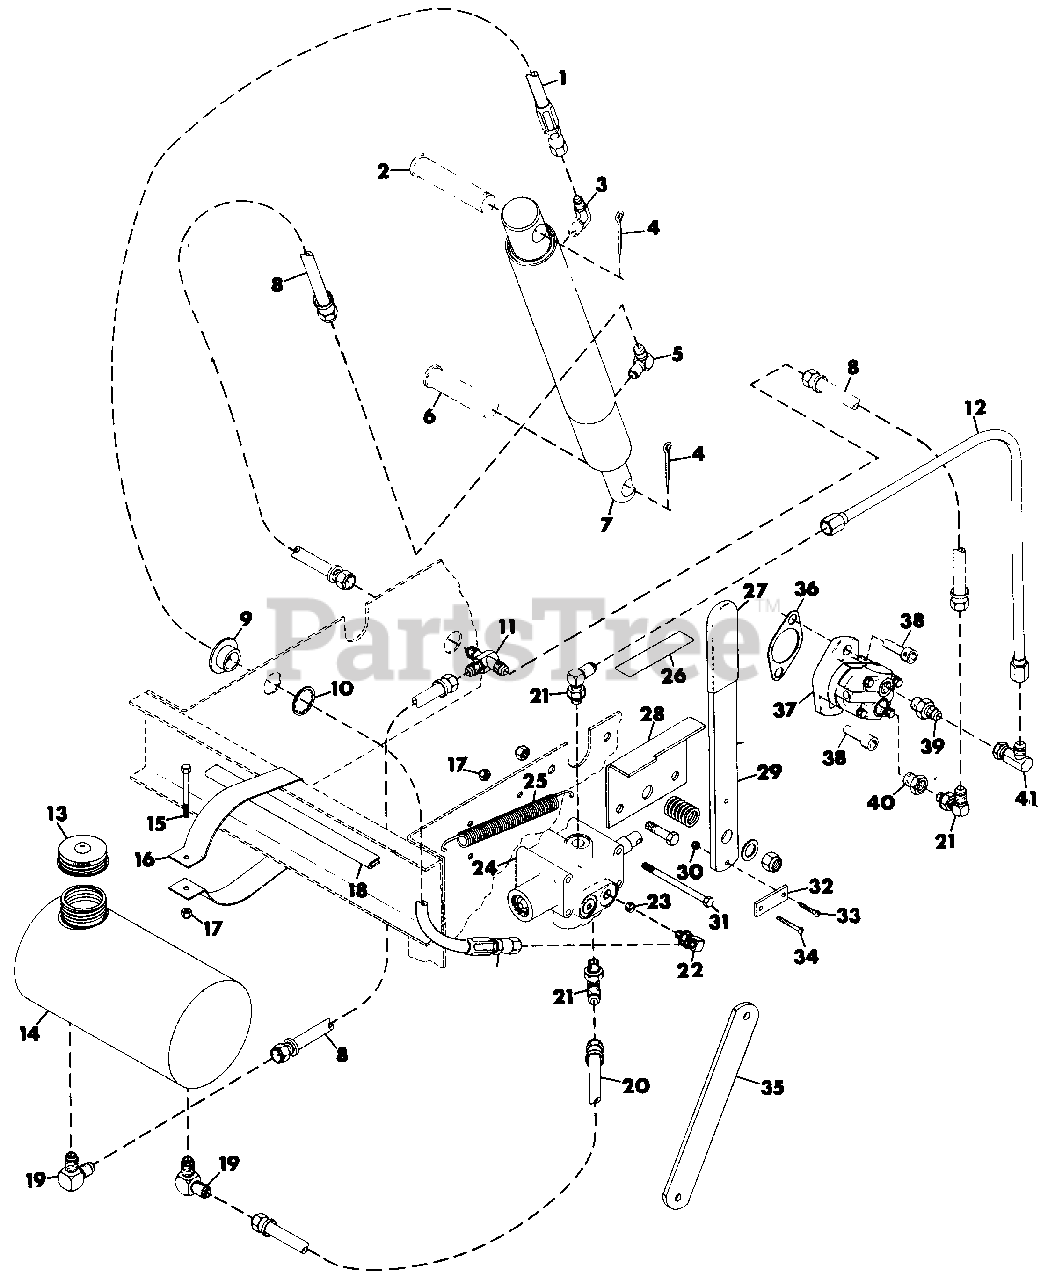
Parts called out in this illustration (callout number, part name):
1	HOSE, HYDRAULIC
2	PIN, CLEVIS
3	ADAPTOR
4	PIN, COTTER .125X1.25
5	ADAPTOR, HYDRAULIC
6	PIN, CLEVIS
7	CYLINDER, HYDRAULIC
8	HOSE, HYDRAULIC
9	BUSHING, NYLON .76X1X.6 FLG.
10	RING, RETAINING INTERNAL TOOTH
11	ADAPTOR, TEE
12	LINE, HYDRAULIC PUMP TO VALVE
13	CAP, HYDRAULIC TANK
14	TANK, HYDRAULIC
15	BOLT, HEX 1/4-20X1.75
16	STRAP, HYDRAULIC TANK
17	NUT, LOCK 1/4-20
18	MOULDING, TANK
19	ADAPTOR
20	ASSEMBLY, HOSE VALVE TO TANK
21	ADAPTOR
22	ADAPTOR
23	PLATE, FLOW RESTRICTION
24	VALVE, CONTROL
25	SPRING, EXTENSION 5.5X.5X20 RATE
26	DECAL, HYDRAULIC LIFT
27	GRIP, HANDLE
28	BRACKET, LIFT
29	LEVER, LIFT
30	NUT, LOCK 10-24
31	BOLT, HEX 1/4-20X2.75
32	STRAP, VALVE
33	SCREW, MACHINE 10-24X.75
34	SCREW, MACHINE 10-24X1.00
35	BAR, DECK LIFT
36	GASKET, COVER
37	PUMP, HYDRAULIC
38	SCREW, CAP 3/8-16 HEX SOCKET HEAD
39	ADAPTOR
40	BUSHING
41	ADAPTOR
